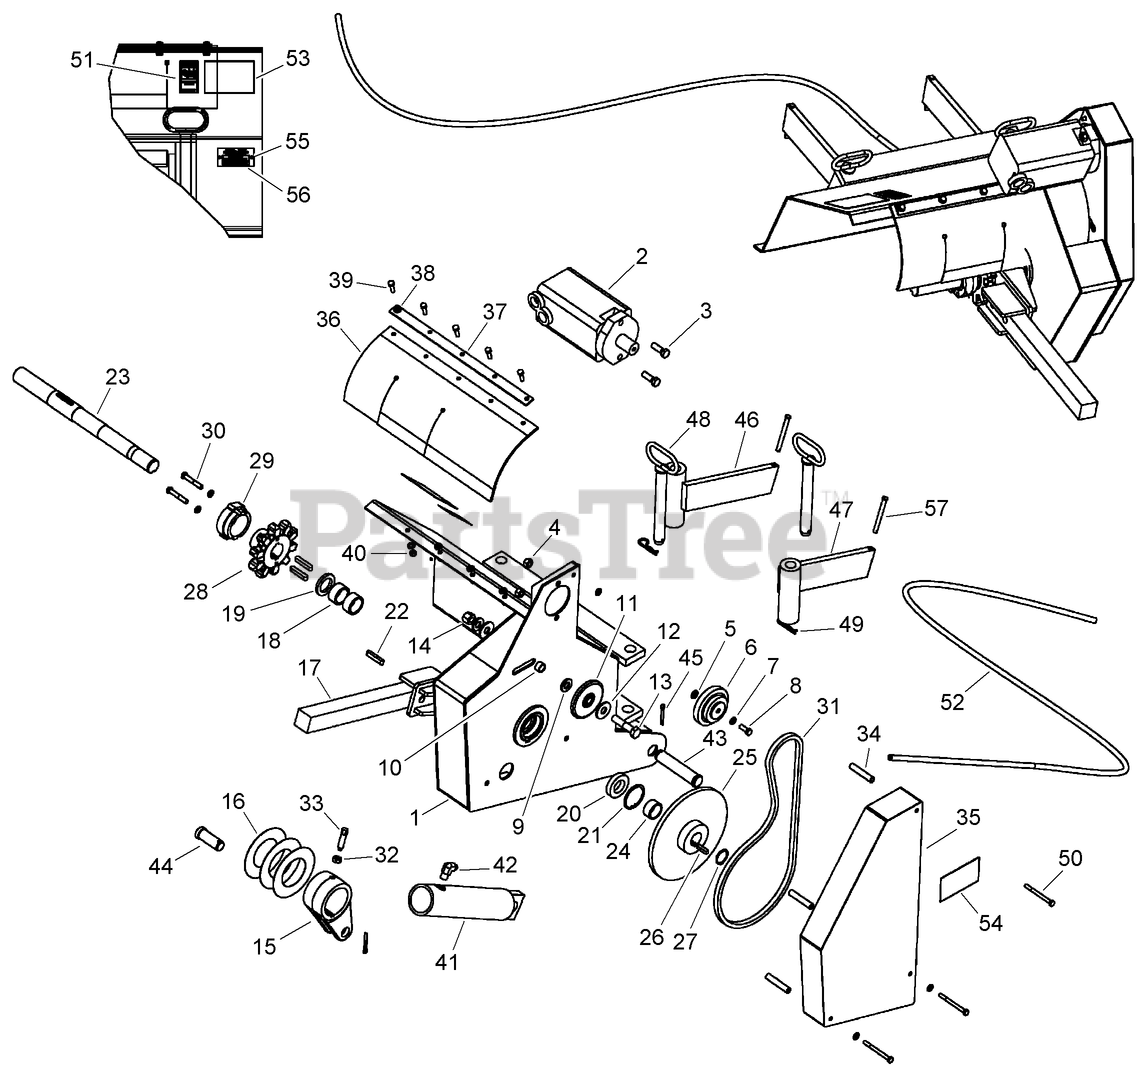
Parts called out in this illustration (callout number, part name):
1	FRAME - Trencher
2	HYD MOTOR ASM
3	SCREW-HH
4	NUT-LOCK, HEX
5	WASHER-0.406 x 0.812 x 0.065 in CST ZND
6	SPROCKET-DRIVE
7	WASHER-Spring Lock, Reg 3/8 ZND
8	SCREW-HH
9	WASHER-FLAT
10	SPACER-SPROCKET, IDLER
11	IDLER BEARING AND SPROCKET ASM
12	WASHER-FLAT
13	BOLT-hex, 5/8 NC x 2-3/4 inch, grade 8
14	NUT-HEX, CENTER LOCK
15	CRANK-BOOM CYLINDER
17	MOUNT-BOOM
18	BEARING-NEEDLE
19	SEAL-OIL
20	BEARING
21	RING - Internal Retaining, No. 244, Bearing Retaining
23	SHAFT-DRIVE, TRENCHER
25	SPROCKET-HEADSHAFT
27	RING-RETAINING
28	SPROCKET
30	BOLT - Hex Hd .375 x 2.25 GR5 ZND
31	CHAIN-68P
33	SCREW-SET, DOG POINT
35	COVER - Chain
36	FLAP-DIRT
37	STRIP-BACK
38	WASHER-FLAT
39	SCREW-HH
40	NUT-Prev Trq 5/16 GRA CAD NONDIR
41	HYD CYLINDER ASM
42	ELBOW - 90, 37FL 3/8 Tube x 3/8 NPFT
44	PIN-CLEVIS
45	PIN-COTTER
46	ARM - RH Mounting
47	ARM - LH Mounting
48	PIN - Mounting
49	PIN-Hair
51	DECAL - Utility Contact Hazard
52	HOSE - 2250 mm (88-5/8 inch) Long, Lower Right-hand Port of Selector Valve to Rod End of Trencher Lift Cylinder
53	DECAL-Danger, Sharp Parts (small)
54	DECAL - Warning, Moving Chains
55	TACK-FASTENER, STEEL
56	PLATE - Serial Number
57	PIN-CLEVIS
